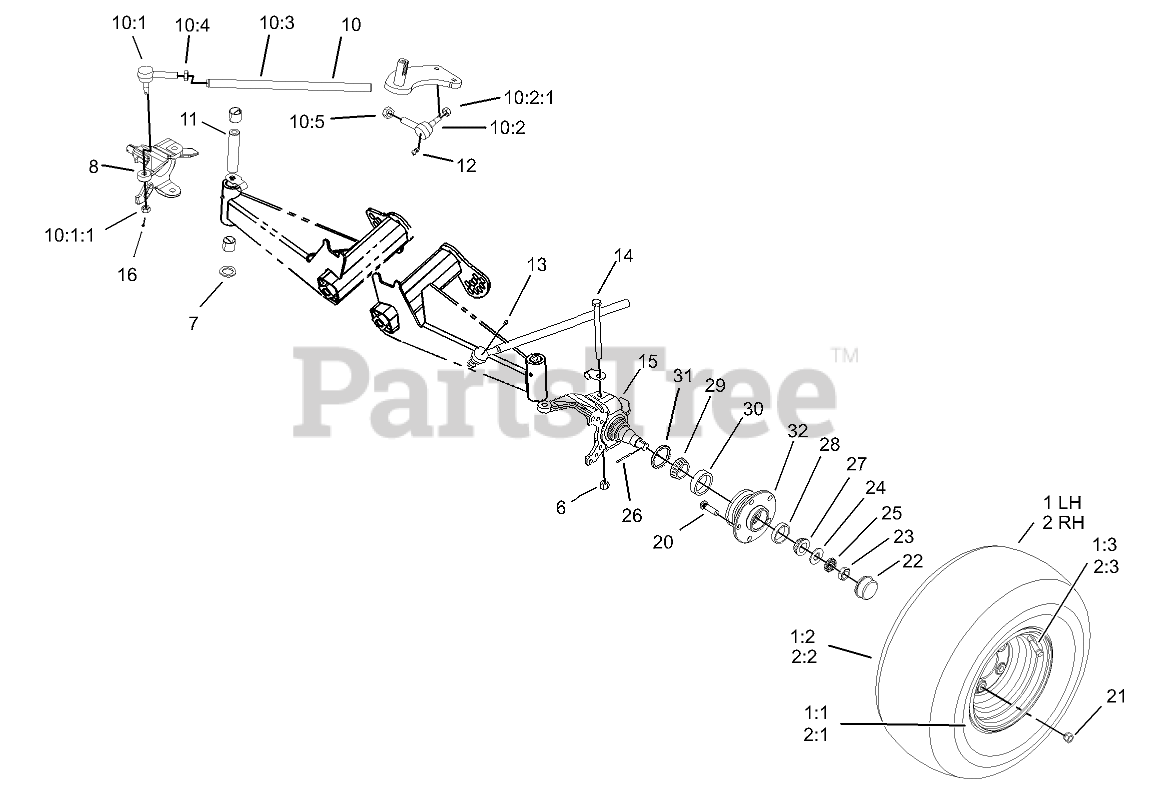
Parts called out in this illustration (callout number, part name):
1	TIRE AND WHEEL ASM
1:1	WHEEL-5 BOLT
1:3	STEM-VALVE
2	TIRE AND WHEEL ASM
2:1	WHEEL-5 BOLT
2:3	STEM-VALVE
6	NUT-LOCK, NI
7	WASHER-THRUST
8	SPINDLE-DISC, RH
10	Rod-Tie
10:1	SOCKET-BALLJOINT
10:2	SOCKET-BALLJOINT
10:3	ROD-TIE
10:4	NUT-JAM
10:5	NUT-JAM
11	SLEEVE-KINGPIN
12	FITTING-GREASE
13	FITTING-GREASE
14	SCREW-HH
15	SPINDLE-DISC, LH
16	PIN-COTTER
20	STUD-TYPE, DRIVE
21	NUT-LUG
22	CAP-DUST
23	NUT-JAM
24	WASHER-TAB
25	NUT-LOCK, RETAINER
26	PIN-COTTER
27	BEARING-CONE, TAPERED
28	BEARING-CUP, TAPERED
29	CONE-BEARING, TAPERED
30	CUP-BEARING, TAPERED
31	SEAL-BEARING
32	HUB
